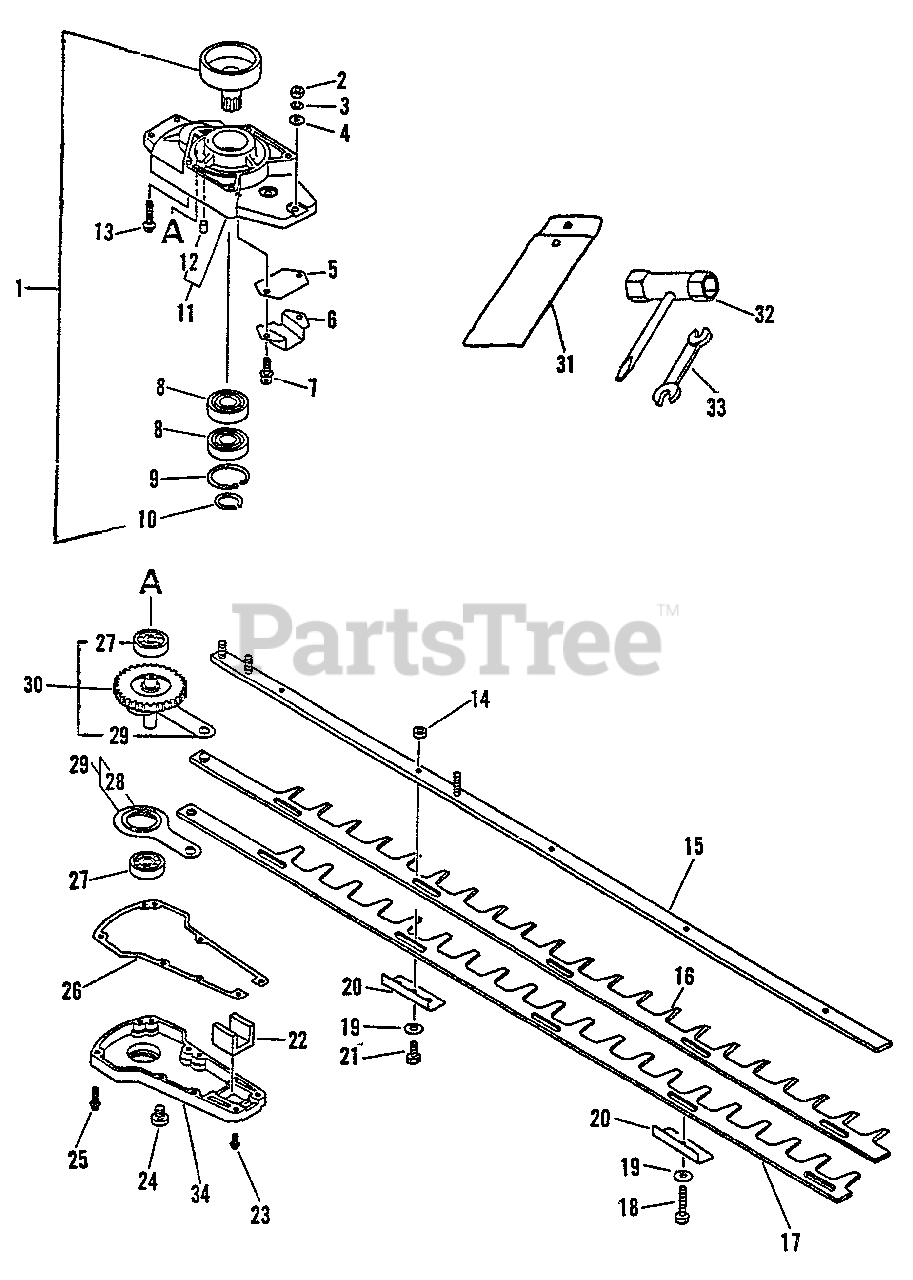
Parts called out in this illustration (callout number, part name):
1	DRUM, CLUTCH
2	LOCKNUT - 6
3	LOCKWASHER - 6
4	WASHER - 6
5	PLATE, GUIDE
6	GUIDE
7	SCREW - 5X14
8	BEARING, BALL - 6003
9	RING, RETAINING - 35
10	RING, RETAINING - 16
11	CASE, GEAR
12	PIN - LOCATING
13	SCREW - 5X30
15	SUPPORT, BLADE
16	BLADE - UPPER
17	BLADE - LOWER
20	INSULATOR
22	SEAL, FELT
23	SCREW - 4X14
24	BOLT - 8X8
25	SCREW - 4X22
26	GASKET, GEAR CASE
27	BEARING, BALL - 6200
28	BEARING, NEEDLE
29	CONNECTING ROD ASSY
30	GEAR ASSY
31	BAG, TOOL
32	T-WRENCH - 14X19mm
33	SPANNER - 8X10mm
34	LID, GEAR CASE
